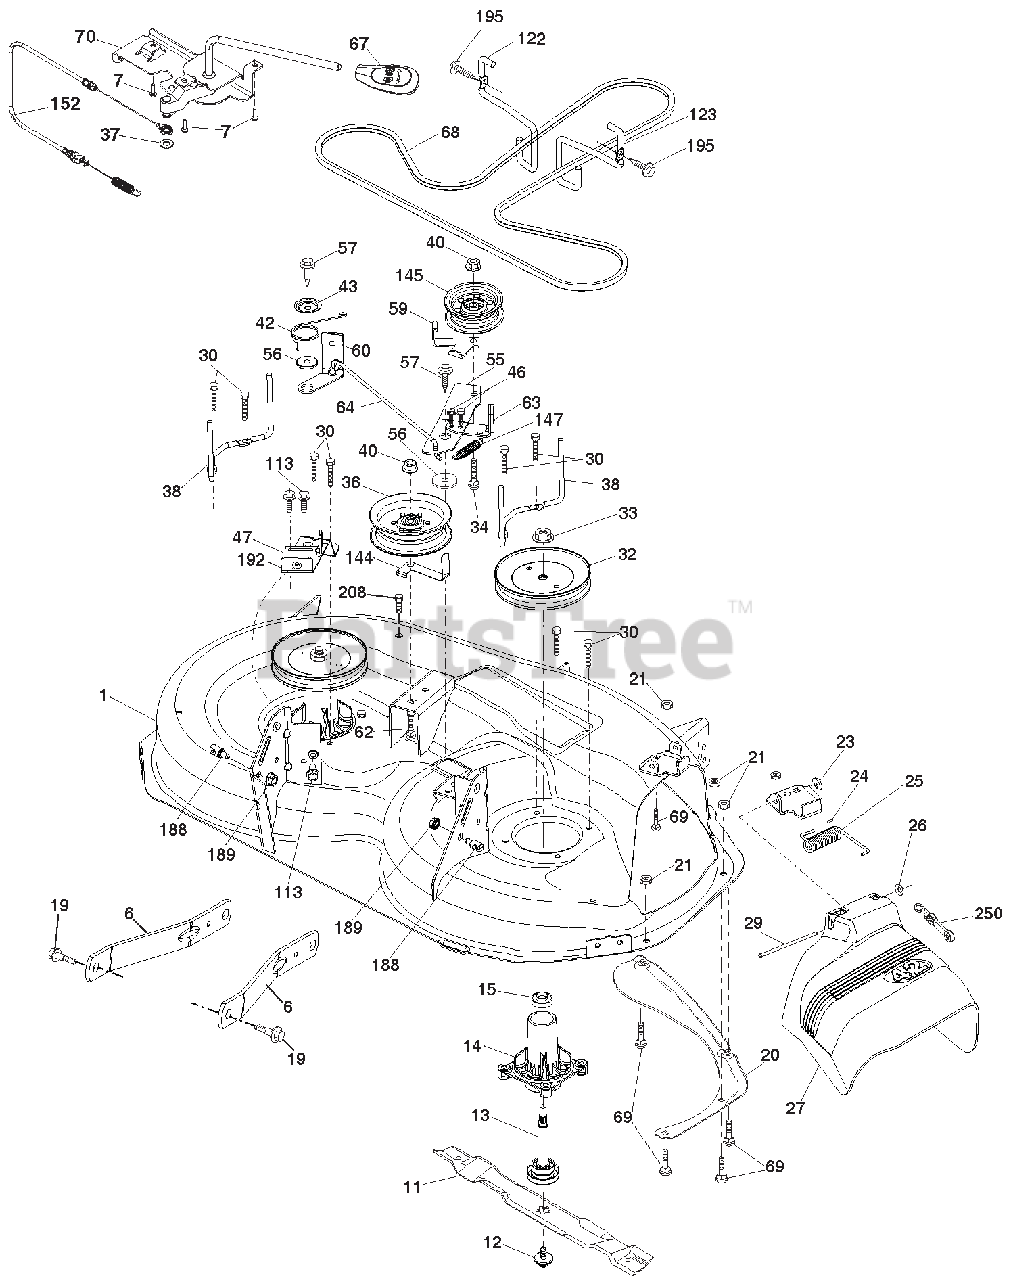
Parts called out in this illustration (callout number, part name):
1	DECK.WELDMENT.42"N/GWB
6	ARM.SUSPENSION.MOWER.REAR.LD
11	BLADE.MOWER.42"HI LIFT PREMIUM
12	SCREW 7/16-20 X 1
13	SHAFT ASM
14	HOUSING.MANDREL.4PT.SERVICE
15	BEARING
19	BOLT.SHOULDER
20	BAFFLE.VORTEX.42.STD/HEAVY DTY
21	Nut, Hex, Crownlock 5/16-18
23	BRACKET.DEFLECTOR.38/42"2005
24	CAP.SLEEVE..80X.112.BLK.MOWER
25	SPRING.TORSION.DFL.38/42/46.GR
26	NUT.PUSH.PHOS.& OIL
27	SHIELD.DEFLECTOR.
29	ROD.HINGE.42/46"
30	SCREW.THD ROLL.DOD PT.HEX
32	PULLEY.MANDREL.5.438 PD.42"
32	MANDREL ASM
33	NUT.FLANGE.LOCK.TOP
34	BOLT.CARR.SH.3/8-16X1-1/2.GR5
36	PULLEY.IDLER.4.50.RAW
37	WASHER.13/32 X 13/16 X 16 GA.
38	KEEPER.BELT.MANDREL.PULLEY
40	Nut, Hex, Flangelock 3/8-16
42	SPRING.TORSION.BRAKE
43	SPRING.TORSION.RETAINER
46	SCREW.THD.ROLL.1/4-20 X 5/8
47	BRACKET.CLUTCH.CABLE
55	IDLER.ARM
56	SPACER.RETAINER
57	SCREW.3/8-16X1.SMGML.TAP/R.BLK
59	GUARD.TUV.IDLER
60	ARM.BRAKE.MOWER.42"
62	BOLT.RD.HD.SQ.NK.3/8-16UNC X 2
63	ARM.BRAKE.MOWER
64	LINKAGE.BRAKE
67	HANDLE.CLUTCH.CABLE.LT TEX.428
68	BELT.DRIVE.100.97"
69	BOLT.RDHD.SQNK.5/16-18 X 5/8
70	CLUTCH ASM.
113	BOLT.5/16-18HEX.WHS.HD.LCKSERR
122	KEEPER.BELT.ENGINE.LH.LT.TEX
123	KEEPER.BELT.PNT.ENG.LH.LT.TEX
144	KEEPER.BELT.MOWER
145	PULLEY.IDLER 48"PRIMARY
147	SPRING.RETURN
152	CABLE.CLUTCH.MANUAL
188	STUD.FASTNER.W/'D'ANTI-ROTATIO
189	Nut, Lock Hex Flange 5/16-18 u
192	BRACKET.BRAKE.STAND.LH
195	SCREW.HEXWSH THDR3/8-16X3/4.BL
208	SCREW.THDROL.3/8-16X1/2.TYT.BL
